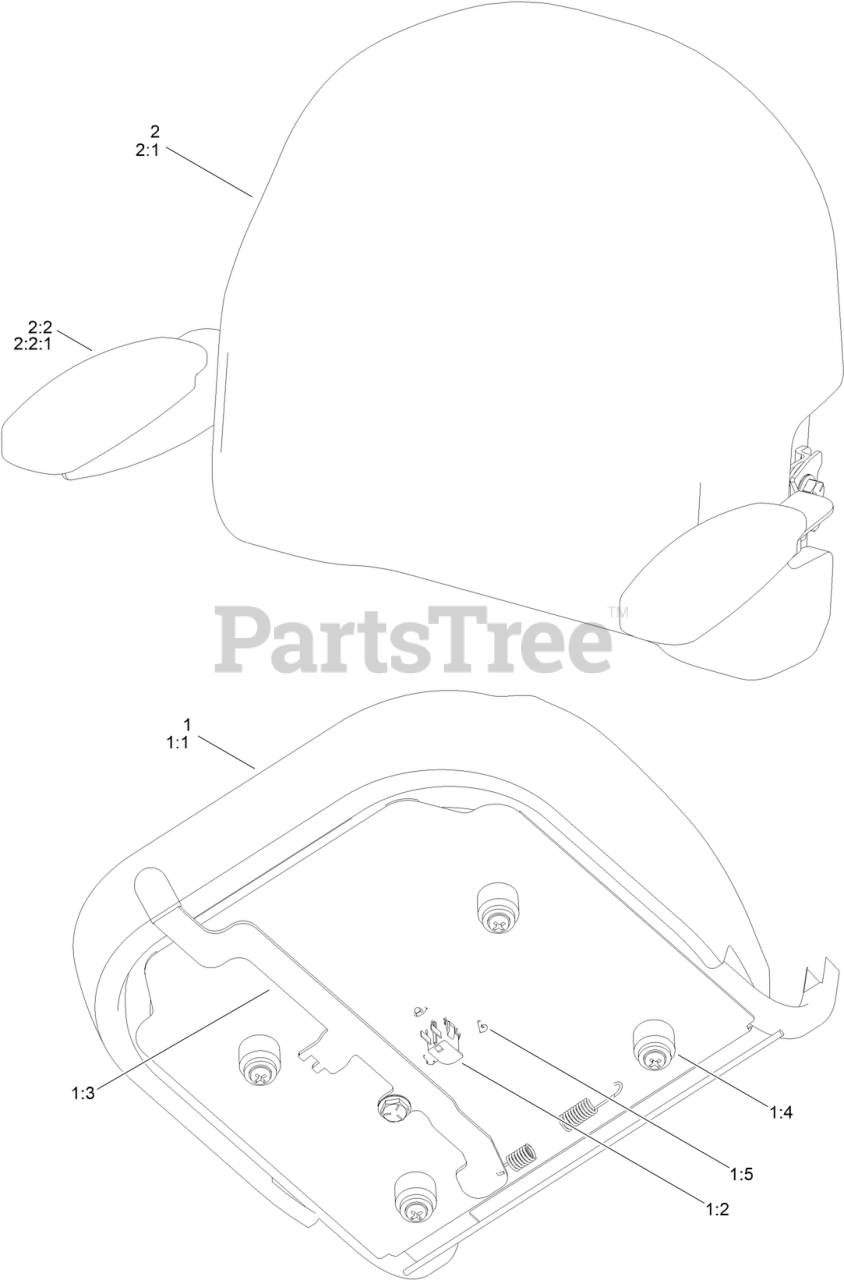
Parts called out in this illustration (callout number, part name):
1	SEAT ASM - BOTTOM
1:1	COVER-SEAT BASE
1:2	SWITCH-BAIL
1:3	TRACK ASM
1:4	BUSHING ASM
1:5	CAP-SWITCH, ACTUATOR
2	SEAT ASM -BACK
2:1	COVER-SEAT BACK
2:2	ARMREST KIT
2:2:1	CUSHION-REST, ARM
